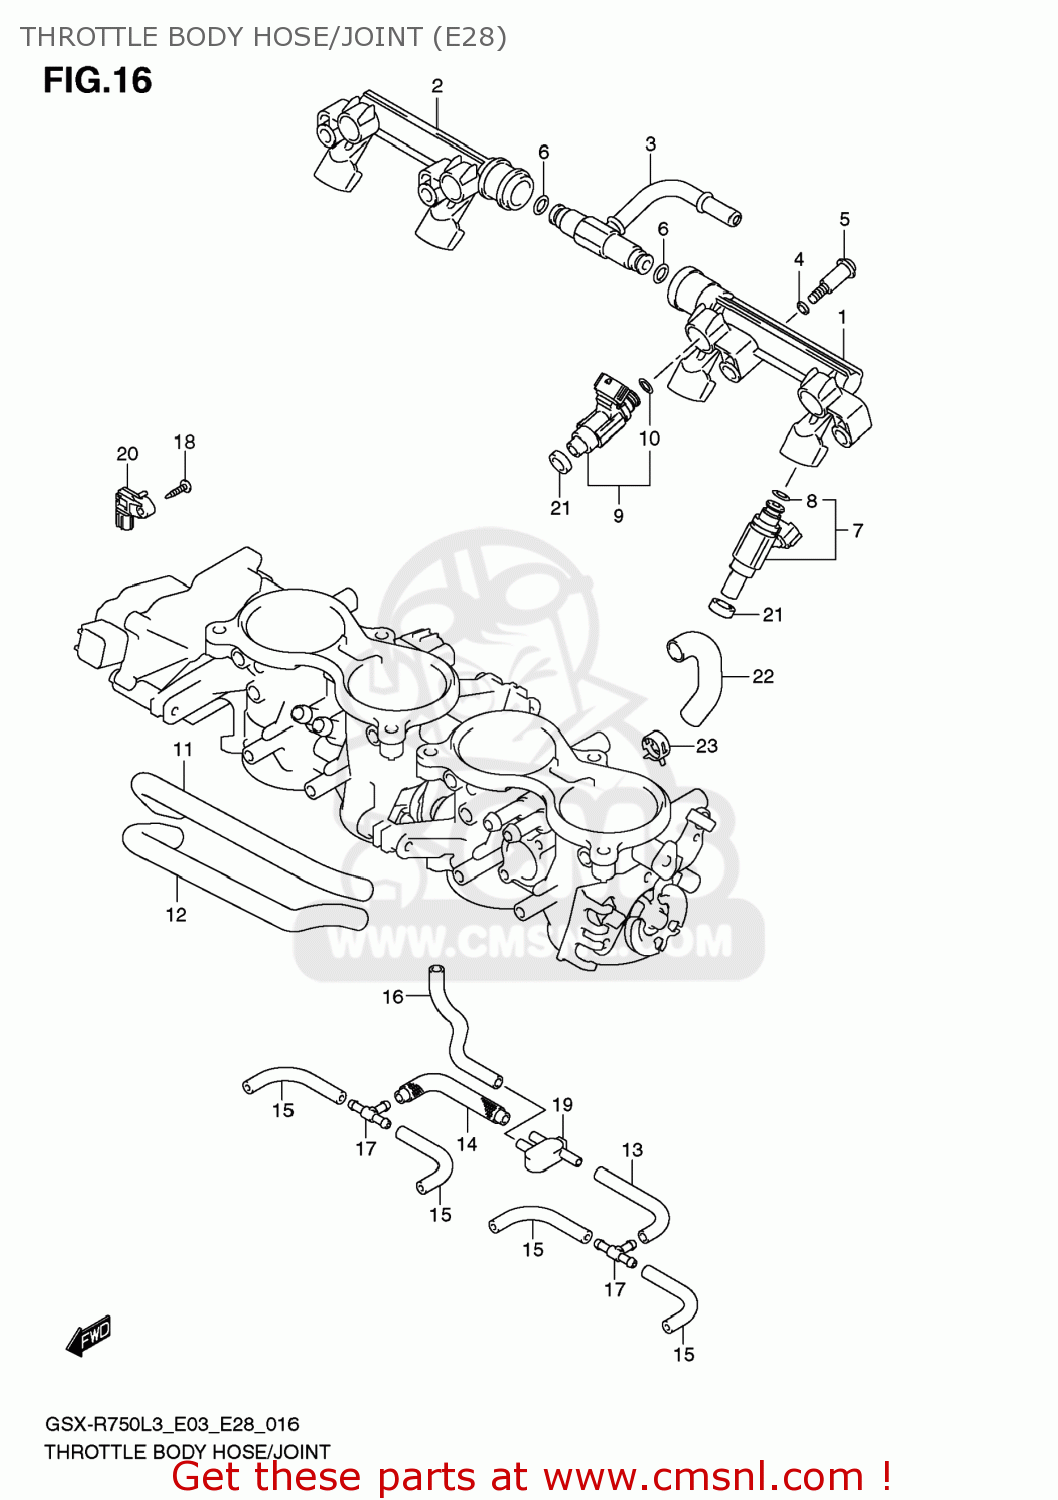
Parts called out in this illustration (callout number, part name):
1	DELIVERY PIPE
2	DELIVERY PIPE
3	NIPPLE ASSY
4	PACKING (NAS)
5	SCREW
6	O RING
7	INJECTOR ASSY
8	O-RING
9	INJECTOR ASSY
10	O-RING
11	HOSE
12	HOSE
13	HOSE
14	HOSE
15	HOSE
16	HOSE
17	3WAY,VACUUM HOSE
18	SCREW
19	JOINT
20	SENSOR,BOOST
21	SEAL
22	HOSE
23	CLIP
